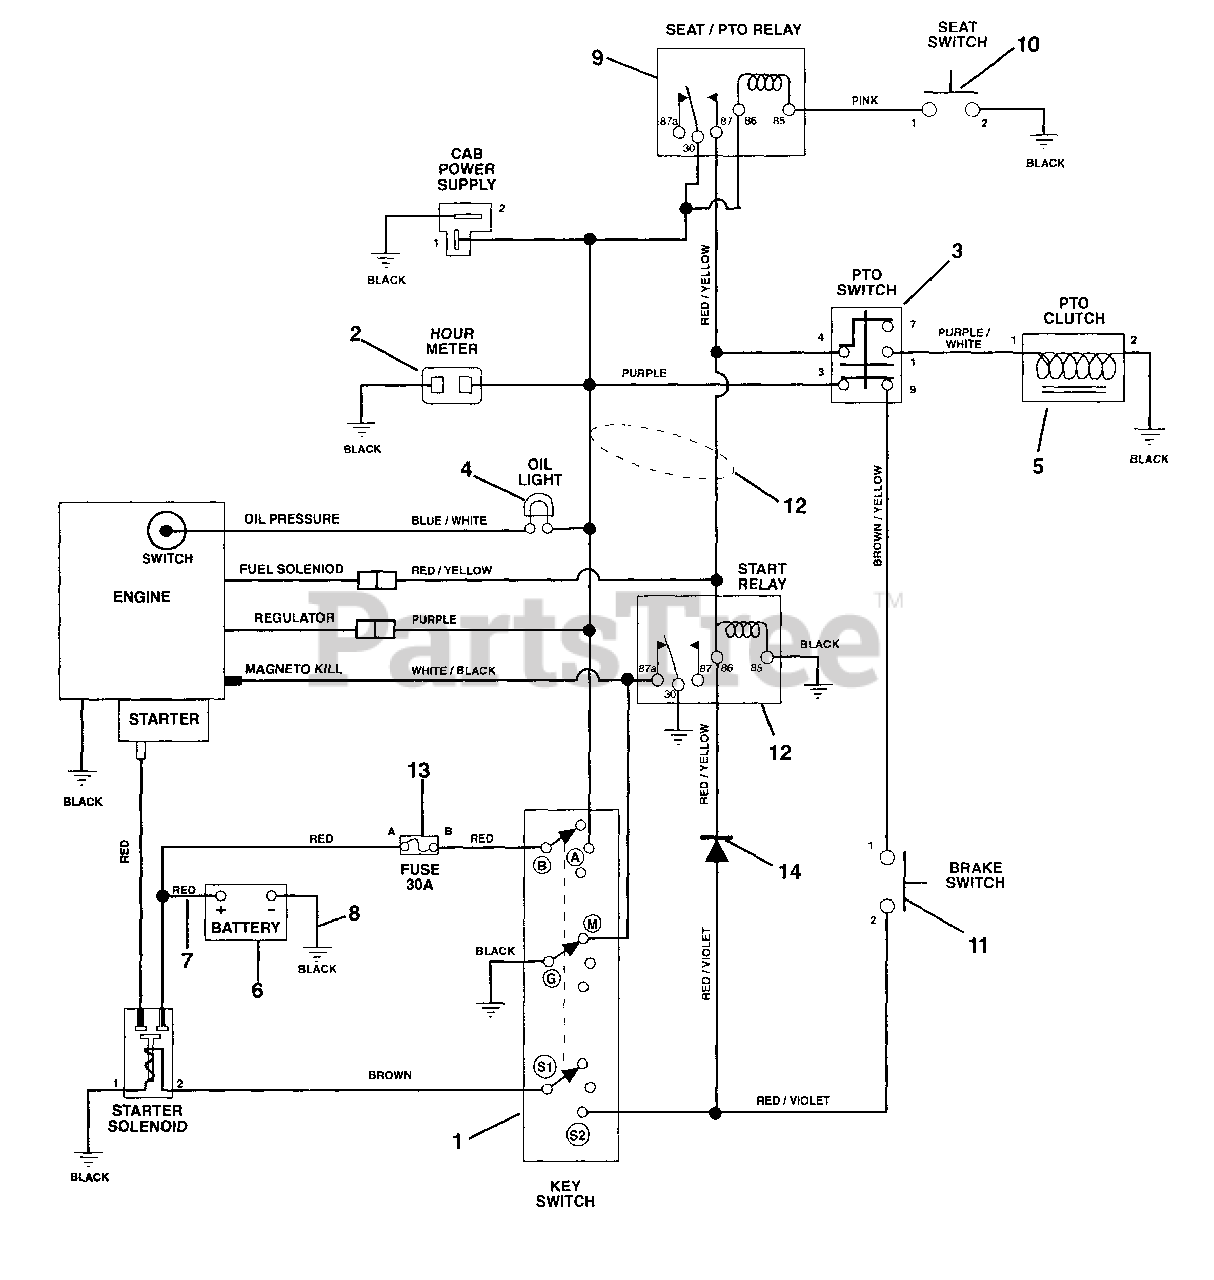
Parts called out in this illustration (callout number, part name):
1	Key Switch
2	Hour Meter
3	Switch-Clutch With Retainer Ring
4	Light-Indicator
5	Electric Clutch
6	Battery with Tube
7	Cable-Battery To Solenoid
8	Ground Cable
9	Relay
10	Seat Switch
11	Switch-Single Pole
12	Harness Kohler
14	Molded Diode Plug-Black 1-Amp
